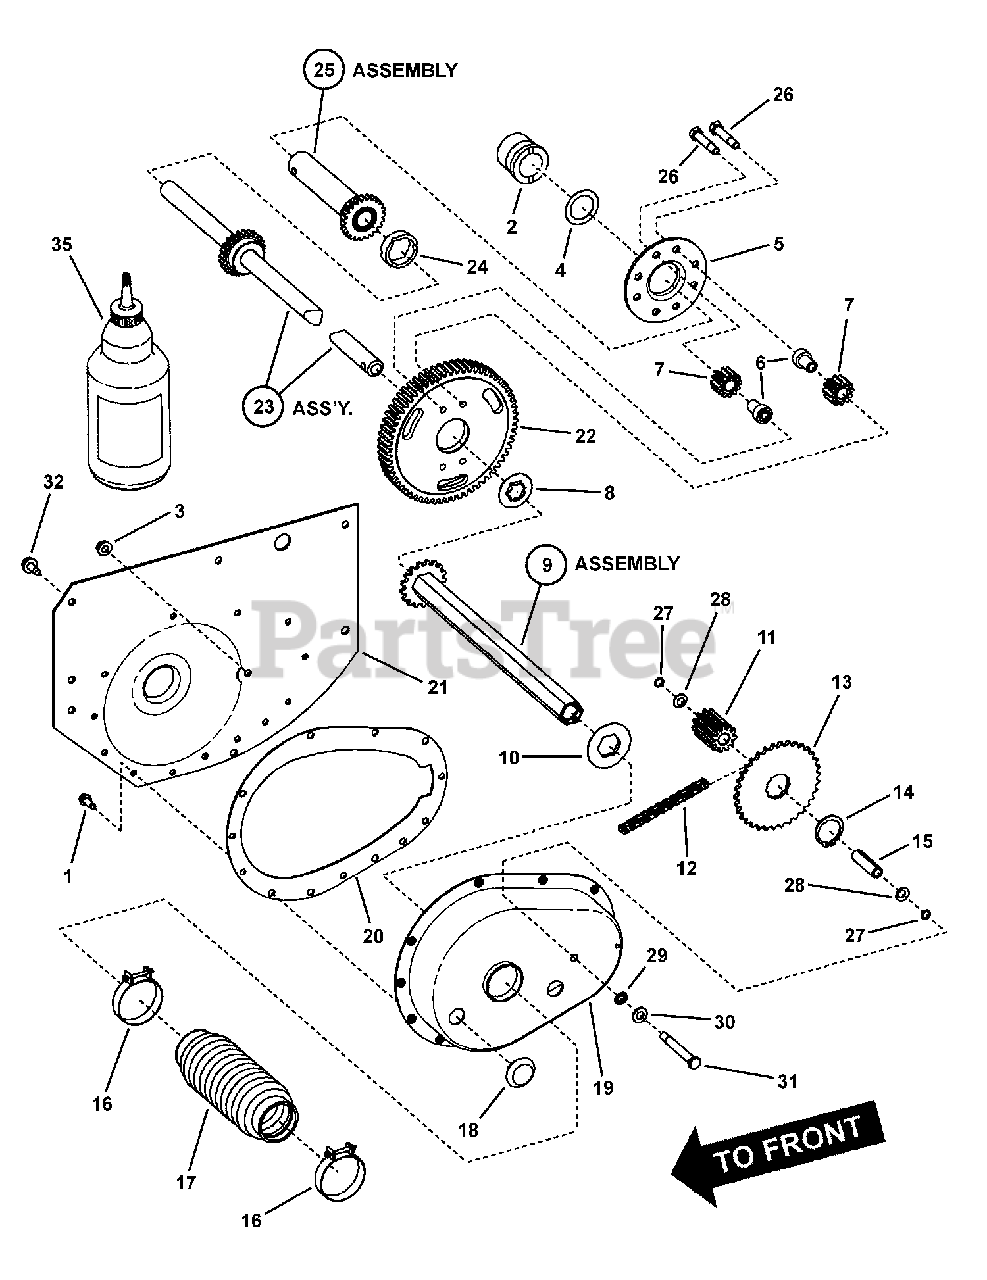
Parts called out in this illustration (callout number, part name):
1	SCREW, 1/4-20 x 5/8" Hex Washer Head Self-Tap
2	BEARING, Axle (R. H. Fender)
3	NUT, 5/16-24 Flange Lock (Large)
4	WASHER, Thrust
5	PLATE, Differential
6	SPACER, Pinion
7	GEAR, Differential Pinion (12T 12P)
8	WASHER, Thrust
9	* ASSEMBLY, Drive Hex Tube
10	WASHER, Nylon
11	GEAR, 11 Tooth, 10 Pitch
12	CHAIN, 46 Pitch (#35 Endless)
13	SPROCKET, 34T, 3/8P
14	RING, 1-3/16" External Retaining
15	SPACER, Differential Case
16	CLAMP, 2" ID
17	BOOT, Rear Axle, Thick Flange
18	PLUG, 1/2" Cup Insert
19	CASE, Transmission
20	GASKET, Transmission Case
21	FENDER, Right Hand (1.62" Dia. Hole)
22	GEAR, 63 Tooth 10 Pitch
23	ASSEMBLY, Long Axle (Includes 23T Gear)
24	SPACER, Differential Case
25	ASSEMBLY, Short Axle (Includes 23T Gear)
26	BOLT, 5/16-24 x 1-5/8" Hex Special Lock (Vibresist)
27	5/16" O-RING
28	WASHER, 5/16" Belleville
29	WASHER, 5/16" External Tooth Lock
30	WASHER, 34 x .69 x .08 Flat
31	SCREW, 5/16-24 x 2-5/8" Hex Head Cap
32	SCREW, 5/16-18 x 5/8" Hex Washer Self-Tap
35	GREASE, "00" Transmission (24 oz. Required)
